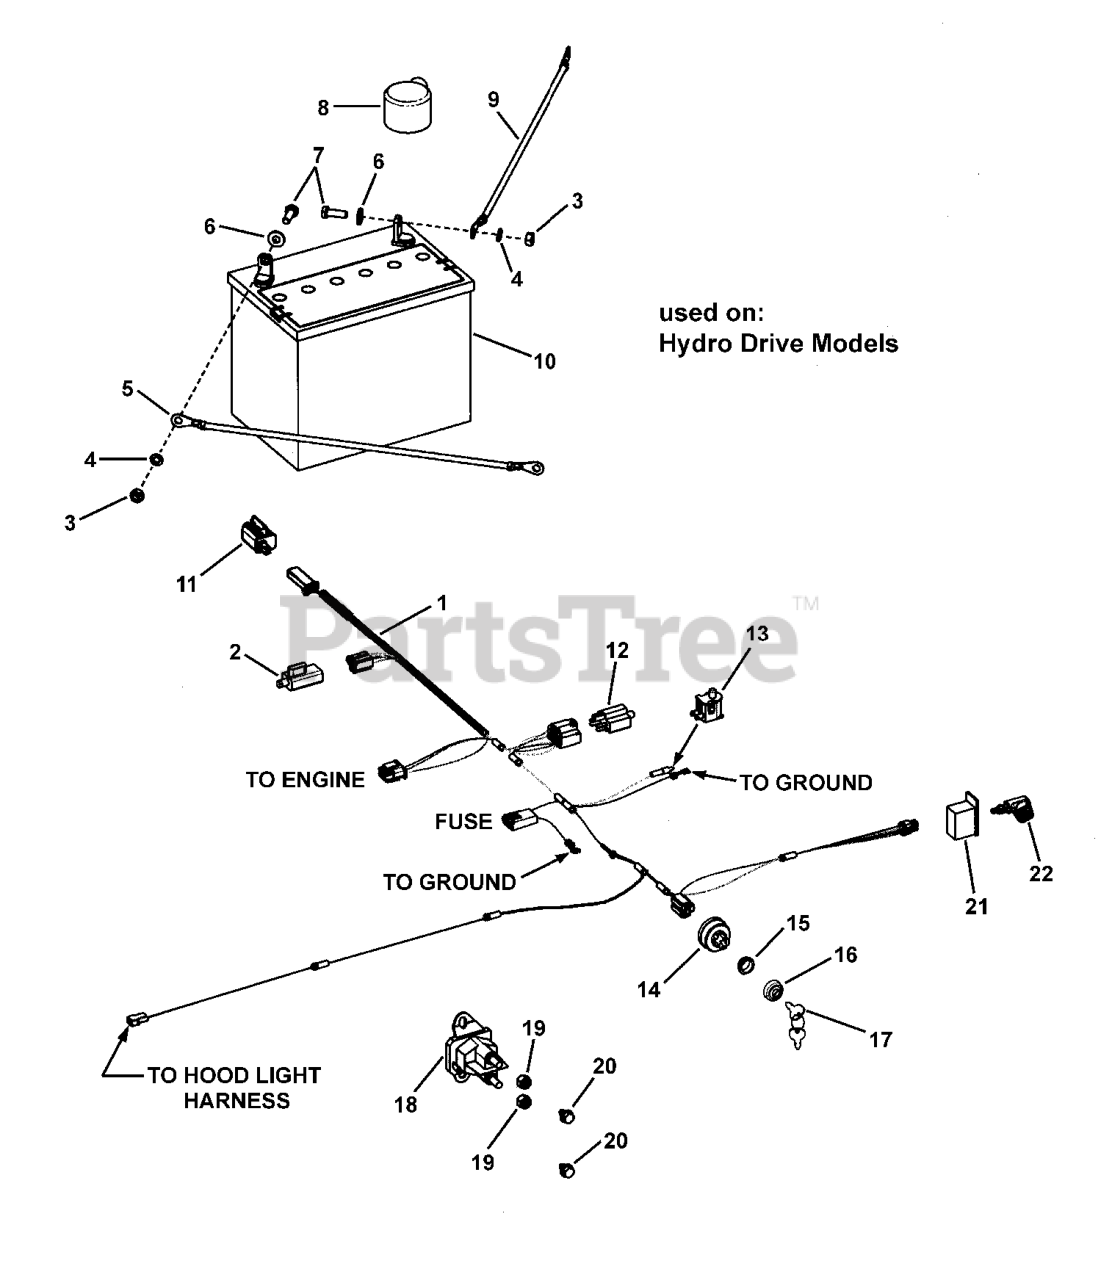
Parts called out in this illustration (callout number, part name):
1	HARNESS, WIRING, HYDRO, TCT, MAN PTO
2	SWITCH, LIMIT, NO/NC, SNAP-IN
3	NUT, HEX 1/4-20 NC-2B YELLOW
4	LOCKWASHER, 1/4
5	CABLE, BAT 8GA 12.00L - BLACK
6	WASHER, 0.250(0.27IDX0.62ODX.05THK)YEL
7	CAPSCREW, HEX HD 1/4-20X0.750 G5 YEL
8	BOOT, BATTERY POSITIVE
9	CABLE, BAT 8GA 18.00L - RED
10	BATTERY KIT, 12 VOLT, 230 CCA
11	SWITCH, LIMIT, NO, SNAP-IN
12	SWITCH, 3 POLE, PLUNGER, SNAP-IN
13	SWITCH, Seat, Push Button (NC)
14	SWITCH, IGNITION-AFTERFIRE SOLENOID
15	NUT, 5/8"-32 E-START
16	CAP, E-START
17	KEY, IGNITION INDAK (SET OF 2)
18	SOLENOID, 3 POLE
19	NUT, HEX LOCK 1/4-20 BZ
20	SCREW, 1/4-14X.38"ST-
21	SWITCH, RMO Module Only
22	KEY, RMO Module Plastic
